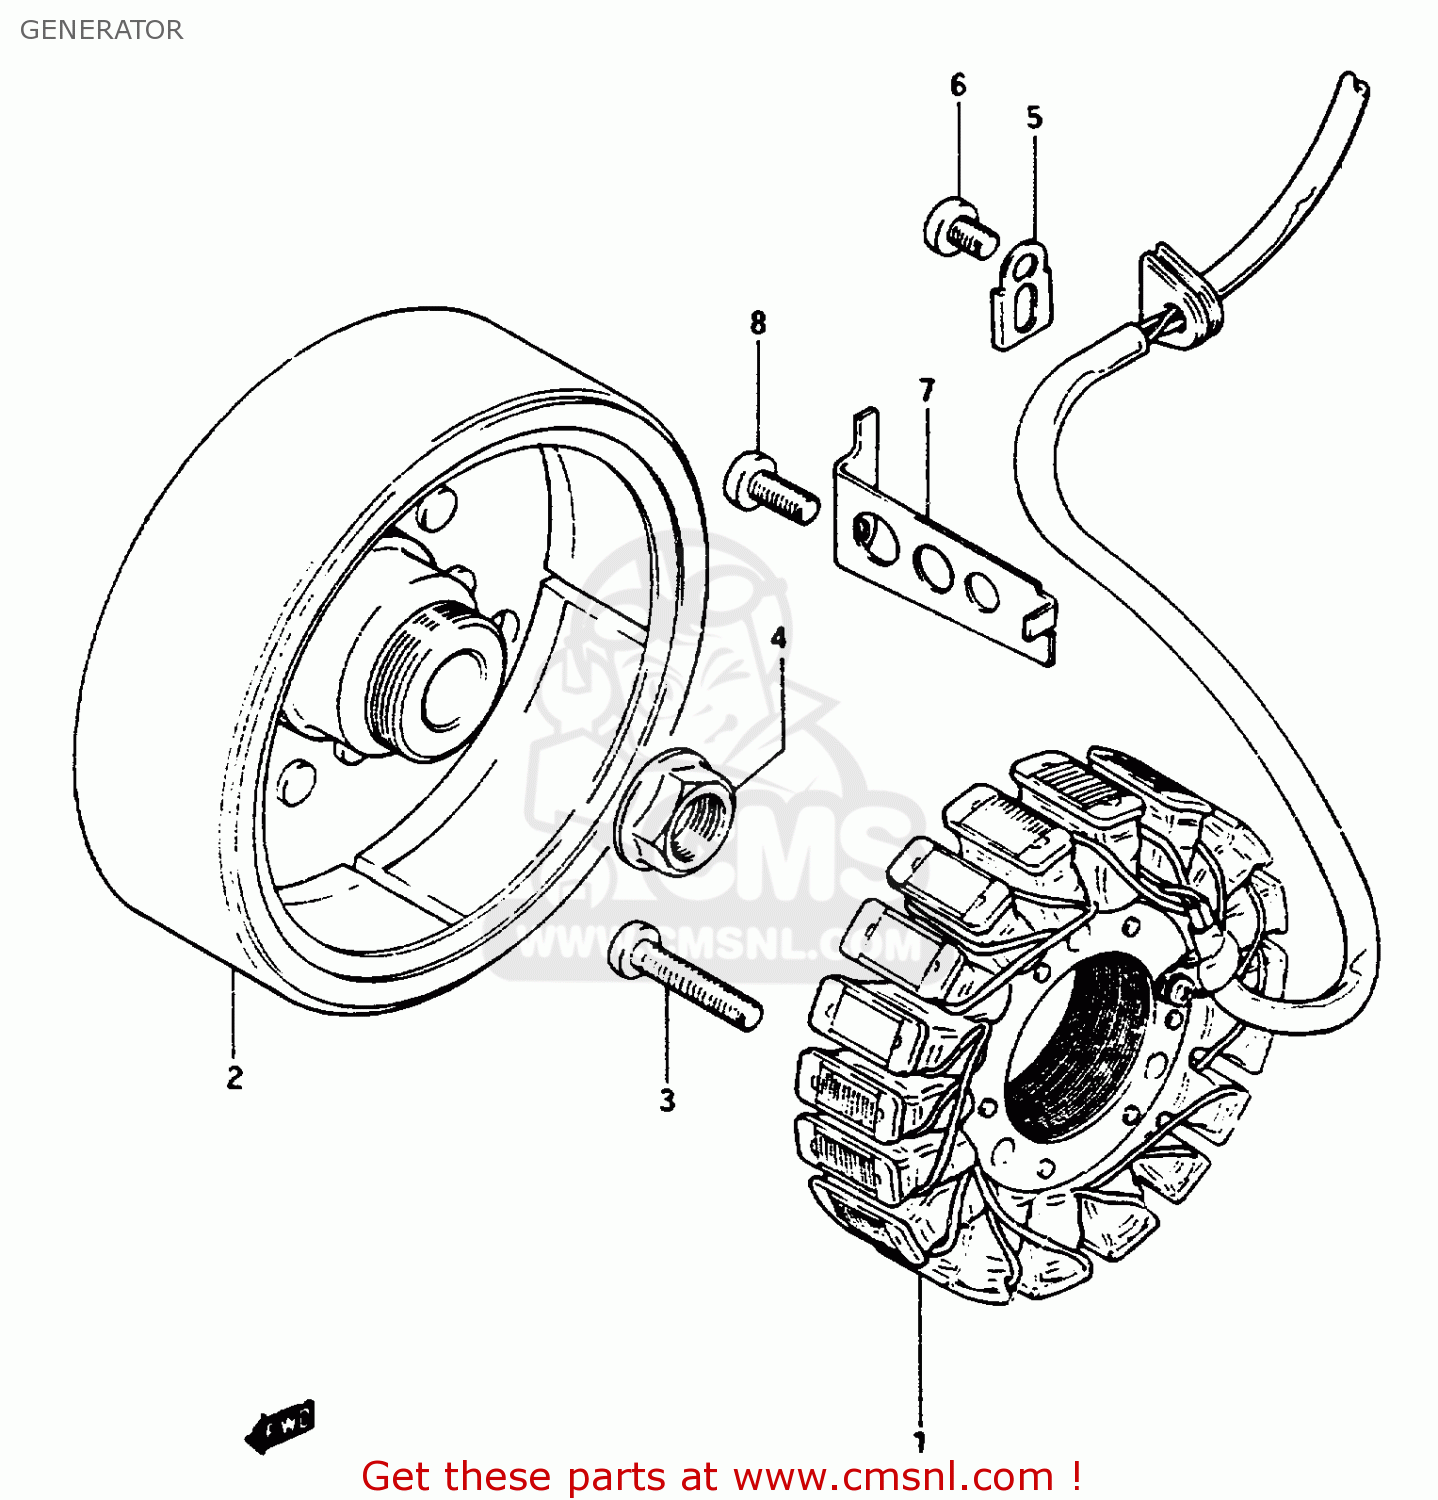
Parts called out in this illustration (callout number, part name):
1	STATOR ASSEMBLY
2	ROTOR ASSY
3	SCREW 6X30
4	NUT,GENERATOR ROTOR
5	CLAMP,GENERATOR LEAD WIRE
6	SCREW
7	CLAMP,GENERATOR LEAD WIRE
8	SCREW
